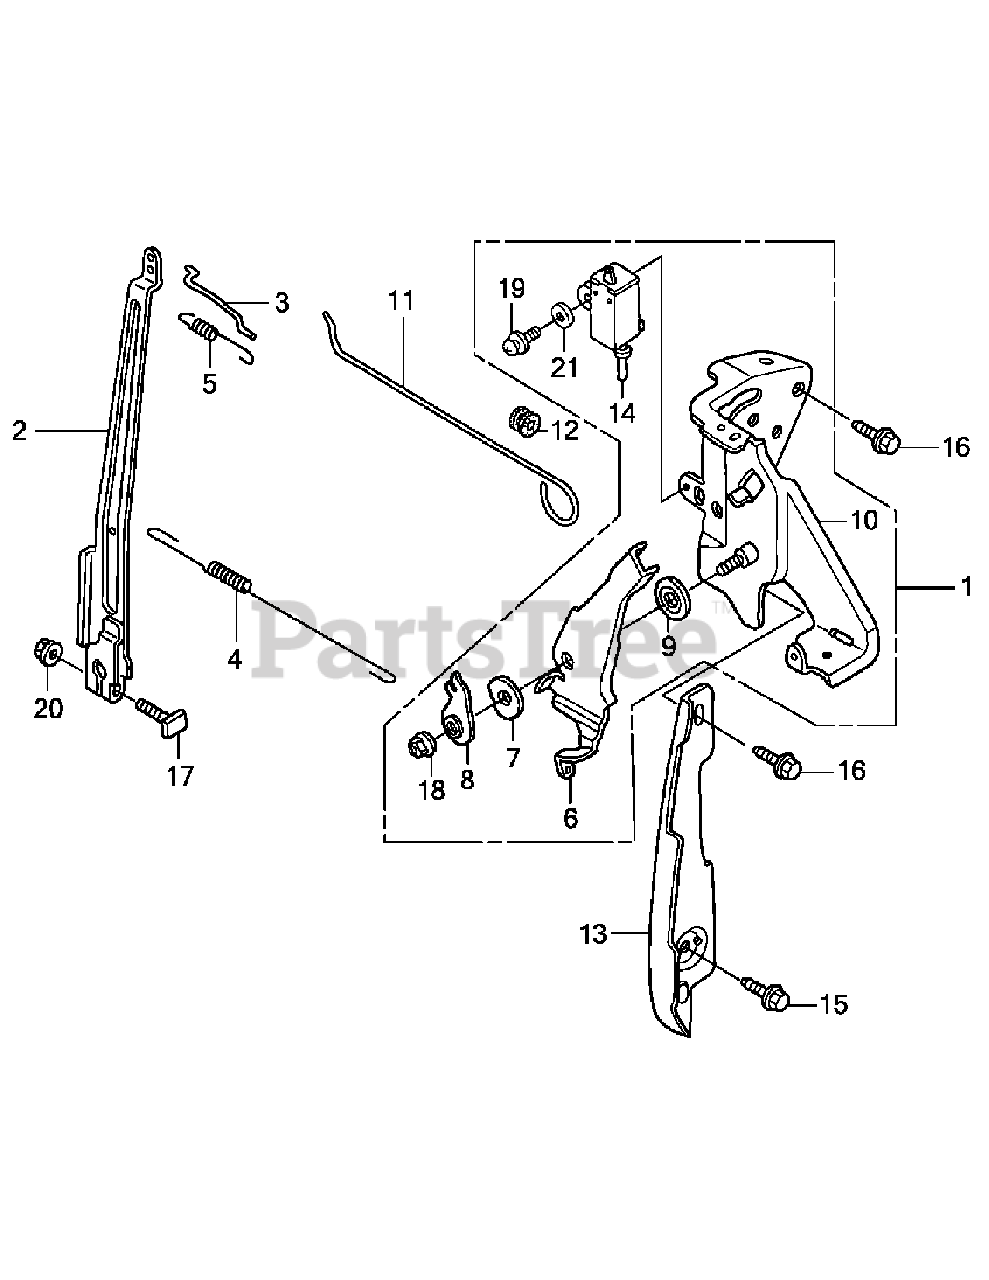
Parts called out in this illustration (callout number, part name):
1	Control Assembly
2	Arm, Governor
3	Rod, Governor
4	Spring, Governor
5	Spring, Throttle Return
6	Lever, Control
7	Spring, Lever
8	Washer, Control Lever
9	Spacer, Control Lever
10	Base Complete, Control
11	Rod, Choke Control
12	Grommet, Choke Rod
13	Plate, Side
14	Switch Assembly, Engine Stop
15	Bolt, Flange 6 x 12 (CT200)
16	Bolt, Flange 6 x 14 (CT200)
17	Bolt, Governor Arm
18	Nut, Self-Lock 6mm
19	Screw-Washer 4 x 12
20	Nut, Flange 6mm
21	Washer, Plain 4mm
